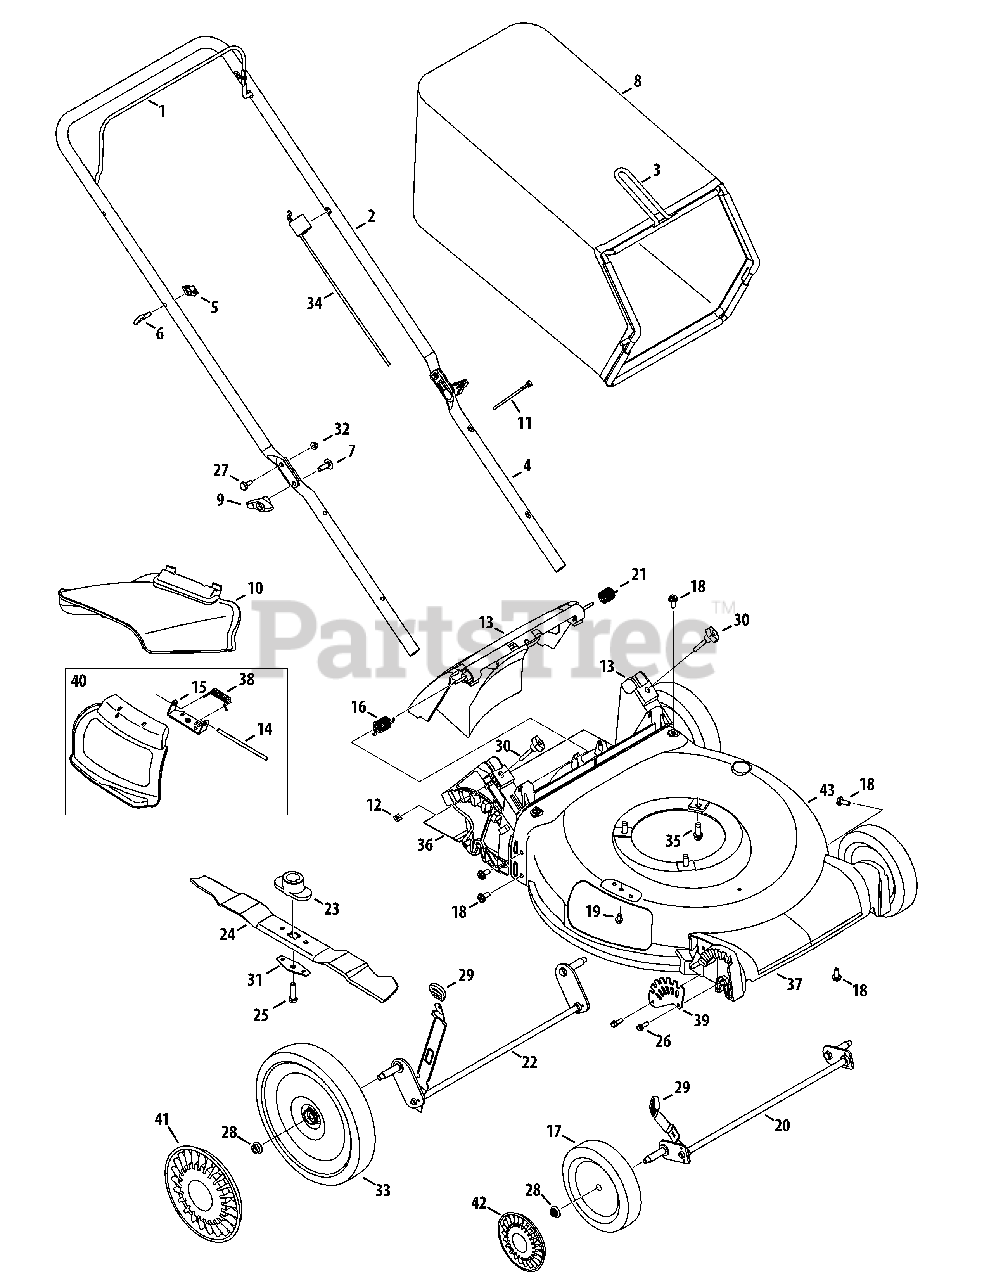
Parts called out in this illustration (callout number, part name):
1	Blade Control, Standard
2	Upper Handle, Adjustable
3	Grass Catcher Frame
4	Lower Handle
5	Wing Nut
6	Rope Guide
7	Carriage Screw ,5/16-18
8	Grass Bag, Black
9	Wing Knob, Black
10	Side Chute
11	Cable Tie
12	Nut, Sq., 1/4-20
13	Rear Discharge Door Assembly
14	Hinge Pin
15	Chute Deflector Bracket
16	Torsion Spring - RH
17	Front Wheel Black
18	Screw, 5/16-14 x .750
19	Screw, 1/4-20 x .500
20	Front Axle Assembly
21	Torsion Spring - LH
22	Rear Axle Assembly
23	Blade Adapter, 25mm x 1.19
24	Mulching Blade
25	Screw , 3/8-24 x 1.50
26	Screw, 1/4-15 x .750
27	Sldr. Screw, .375 x .126 x 1/4-20
28	Flange Lock Nut, 3/8-16
29	Adjustment Lever Knob
30	Wing Nut
31	Blade Bell Support
32	Nut, Flange Lock, 1/4-20
33	Rear Wheel Black
34	Control Cable, 37.58"
35	TT Sems Screw, 3/8-16 x 1.0
36	Trail shield
37	Front Cover
38	Torsion Spring
39	Front Height Adjuster Plate
40	Hinged Mulch Plug Assembly
41	Hubcap, 11"
42	Hubcap, 7" w/o snaps
43	Deck , 21" - Orange
